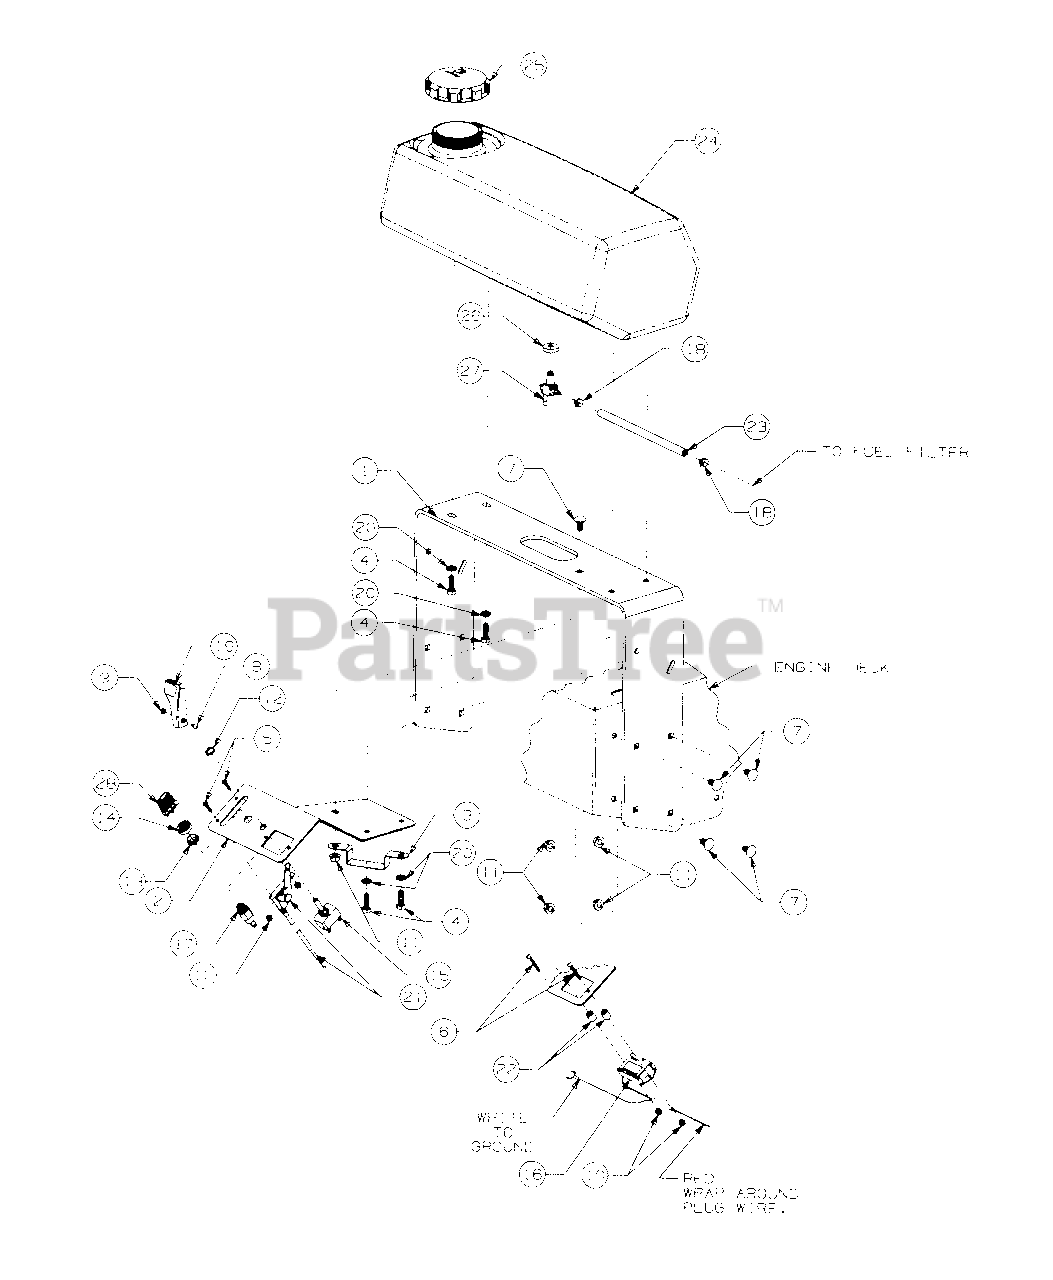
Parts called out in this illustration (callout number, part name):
1	Support, Lower Handle
2	Panel w/Graphic, Control
3	Bracket, Cable Retainer
4	Screw, Hex Cap, 3/8-16 X 1.0 Lg GR5
5	Screw Pan Hd Cutting, #10-24 X .75 Lg
6	Bolt, Pan Head, #10-24 X 1.50 Lg
7	Bolt, Sht Nk Carriage, 3/8-16 X .75 Lg GR5
8	Screw, Cross Rec Truss Hd, #8-32 X .38 Lg
9	Nut, Hex, #8-32
10	Nut, Hex Nylock, #10-24
11	Nut, Hex Flanged Lock, 3/8-16
12	Nut, Hex, 1/2-27 X .100 Thk
13	Nut, Ignition Switch, 5/8-32
14	Cap, Ignition Switch
15	Switch, PTO
16	Meter, Hour/Tach, Model TT226NR-2C
17	Switch, Ignition
18	Clamp, Hose
19	Knob, Throttle Control
20	Washer, Lock, 3/8
21	Control, Throttle
22	Spacer, .315 ID X .50 OD X .52 Lg
23	Line, Fuel - 9" Lg - Order bulk fuel line part no. 759-3330, 10 ft Lg
24	Tank Fuel
25	Cap, Fuel
26	Grommet, Shutoff Valve
27	Valve, Fuel Shutoff
28	Key, Ignition
